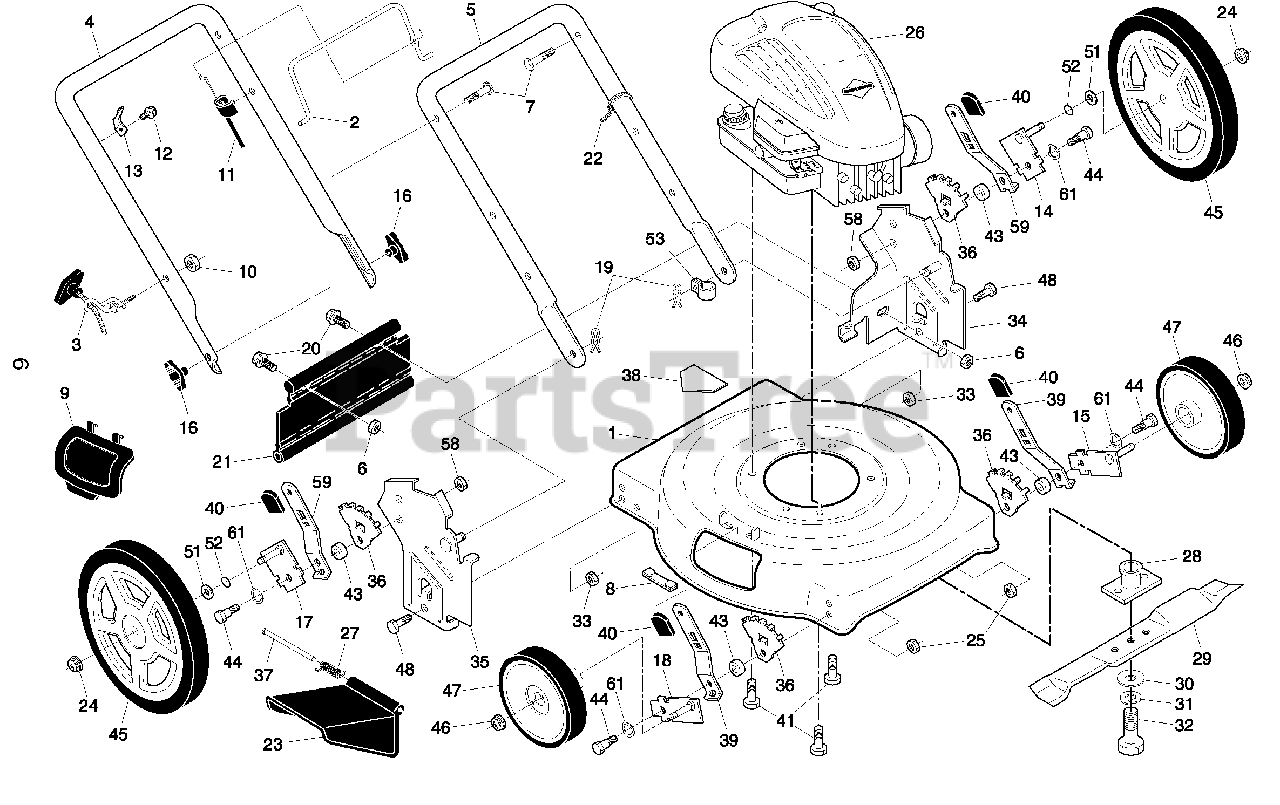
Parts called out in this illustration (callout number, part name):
1	Lawn Mower Housing
2	Control Bar
3	Rope Guide
4	Upper Handle
5	Lower Handle
6	Locknut, Hex 1/4-20
7	Handle Bolt 5/16-18
8	Clip, Closeout
9	Mulcher Plate
10	Nut, Hex 1/4-20
11	Engine Zone Control Cable
12	Hex Washer Head Screw #10-24 x 1/2
13	Up-Stop Bracket
14	Axle Arm Assembly, Rear, LH
15	Axle Arm Assembly, Front, LH
16	Handle Knob
17	Axle Arm Assembly, Rear, RH
18	Axle Arm Assembly, Front, RH
19	Hairpin Cotter
20	Screw, Hex Cap Head 1/4-20
21	Rear Defl ector
22	Wire Tie
23	Discharge Guard
24	Nut, Hex, Flangelock 3/8-16
25	Nut, Hex, Flangelock 5/16-18
27	Torsion Spring
28	Blade Adapter
29	22" Blade
30	Hardened Washer
31	Helical Lockwasher 3/8
32	Screw, Hex Head, Grade 8, 3/8-24 x 1-3/8
33	Nut, Hex, Nylock 5/16-18
34	Wheel Bracket Support, LH
35	Wheel Bracket Support, RH
36	Wheel Bracket Adjuster
37	Hinge Rod
38	Danger Decal
39	Selector Spring, Front
40	Selector Knob
41	Screw, Hex Head, Threaded, Rolled 3/8-16 x 1
43	Spacer
44	Shoulder Bolt 5/16-18
45	Wheel & Tire Assembly, Rear, 12"
46	Nut, Hex, Flangelock 3/8-16
47	Wheel & Tire Assembly, Front, 7"
48	Bolt, Hex Head 5/16-18
51	Washer, Flat 3/8
52	O-Ring
53	Clip, Cable
55	Nut, Hex
59	Selector Spring, Rear
61	Washer, Curved, Cylindrical
61	Operator's Manual, English
61	Operator's Manual, French
61	Repair Parts Manual, English / French
